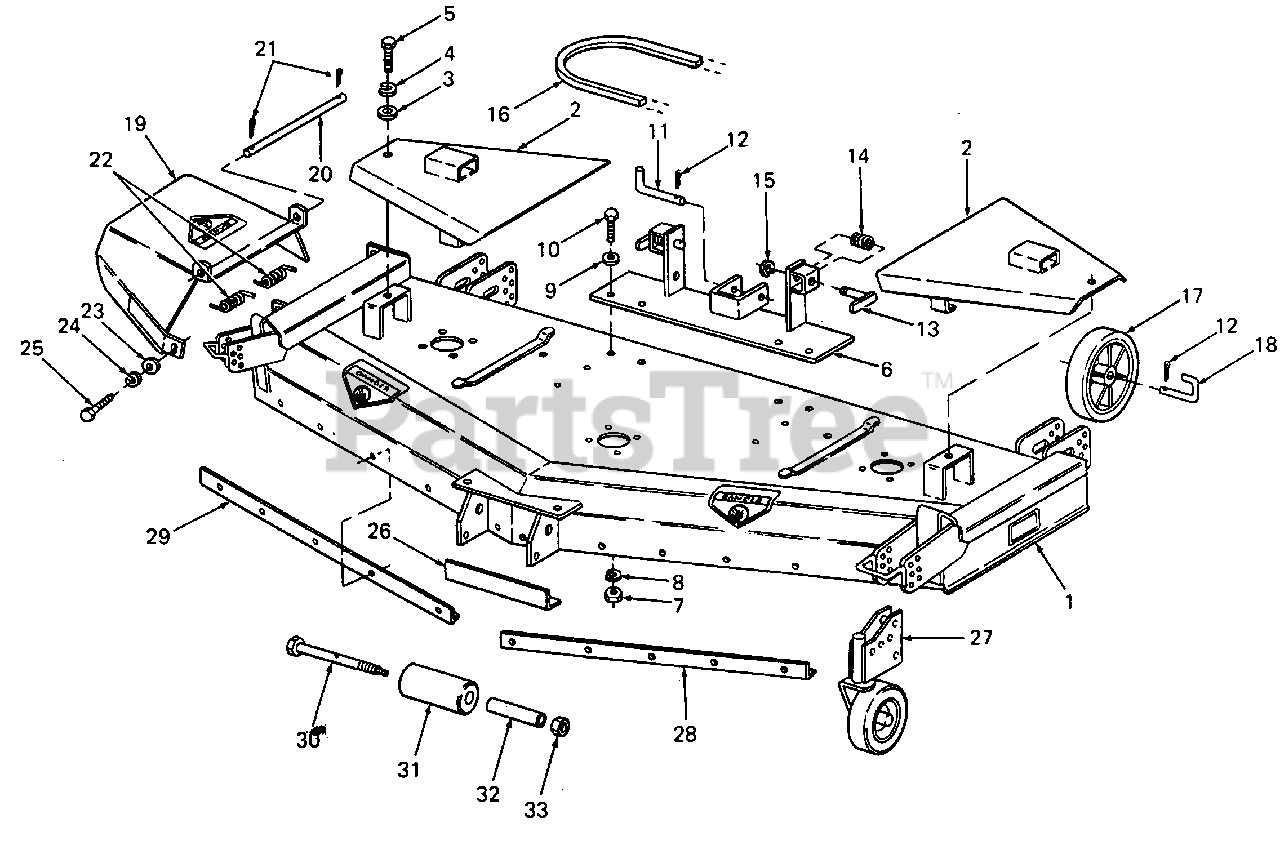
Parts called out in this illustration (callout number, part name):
1	Deck Assy w/Graphics
2	Cover, Deck Belt
3	Washer, Flat, .390 ID X 1.50 OD X 0.75 Thk
4	Washer, Lock, 3/8
5	Screw, Hex Cap, 3/8-16 X 1 Lg GR5
8	Washer, Lock, 1/2
9	Washer, Flat, .531 ID X 1.062 OD X 0.74 Thk
10	Screw, Hex Cap, 1/2-13 X 1.25 Lg GR5
11	Pin, Locating
12	Pin, Quick Attach
13	Pin, Coupler
14	Spring, Coupler
15	Ring, Snap
16	Belt, Spindle Drive
17	Wheel, Rear Gauge, 8"
18	Pin, Rear Wheel Axle
19	Deflector, Chute w/Graphic
20	Rod, Chute Deflector Mounting
21	Pin, Cotter, 1/8 Dia X 1.25 Lg
22	Spring, Deflector
23	Washer, Flat, .438 ID X 1.00 OD X .064 Thk
24	Washer, Lock, 3/8
25	Screw, Hex Cap, 3/8-16 X .75 Lg GR5
26	Up Stop Angle
27	Wheel Assy, Pivoting Gauge - LH
28	Angle, Front Mower, 26" Lg
29	Angle, Front Mower, 33" Lg
30	Bolt w/Fitting
31	Roller, Front
33	Nut, Hex Center Lock, 1/2-13
